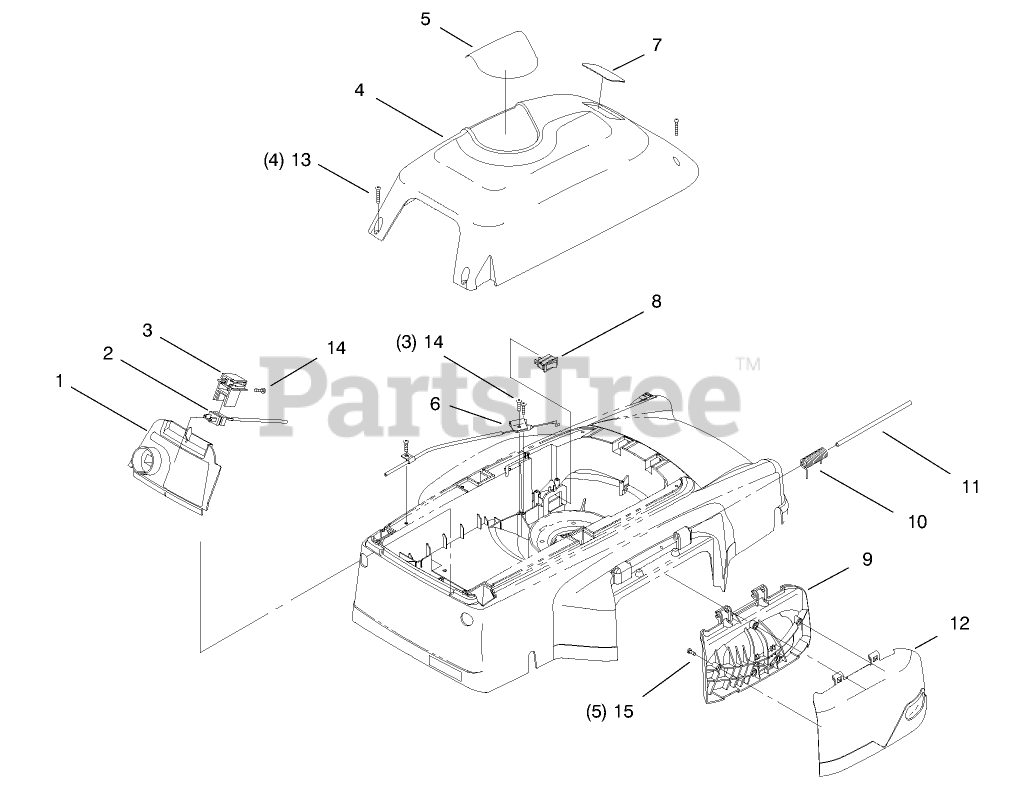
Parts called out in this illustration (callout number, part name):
3	HOUSING - PLUG
4	COVER ASM
6	BRACKET - CABLE
8	SWITCH
11	PIN - HINGE, MULCH PLUG
13	SCREW-PPH
14	SCREW-PPH
15	SCREW
